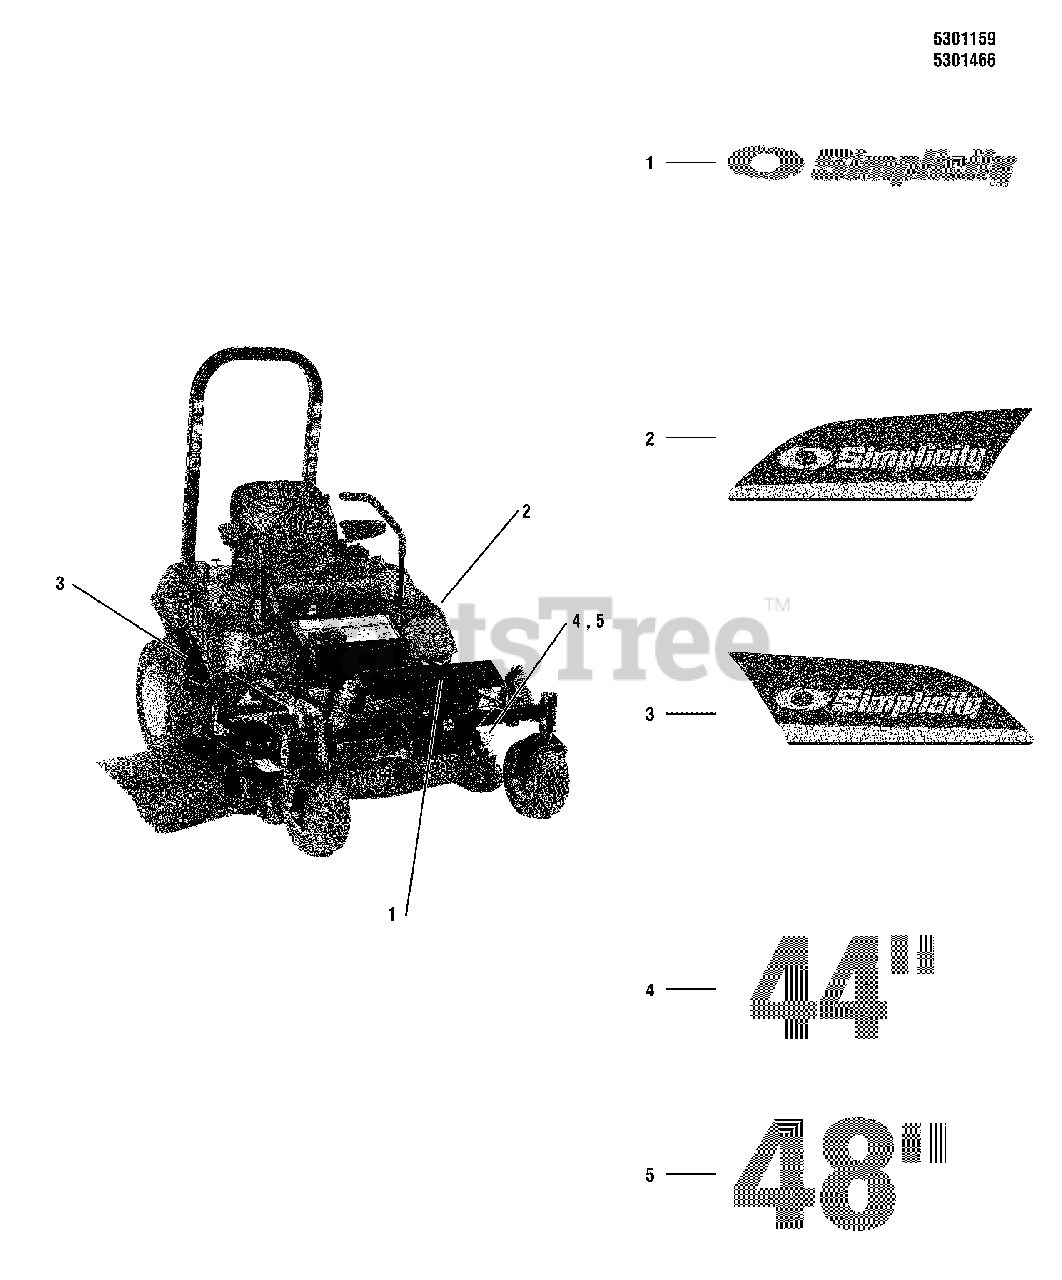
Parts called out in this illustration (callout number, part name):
1	DECAL-SIMPLICITY SILVER & BLUE W/ICON
2	DECAL, BADGE, LH
3	DECAL, BADGE,RH
4	DECAL, 44
5	DECAL, 48
